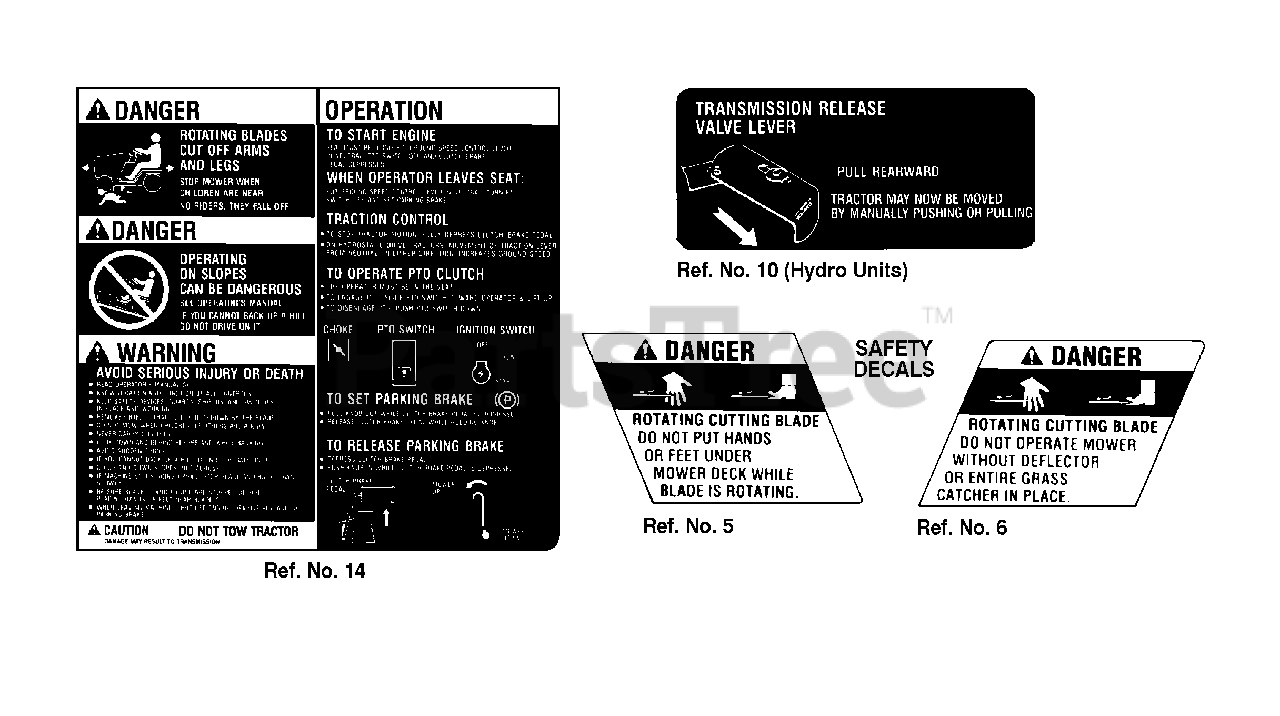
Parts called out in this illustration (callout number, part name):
5	DECAL, Danger (Hand under deck)
6	DECAL, Danger (Chute in place)
10	DECAL, Release Valve
14	DECAL, Operating Instructions
